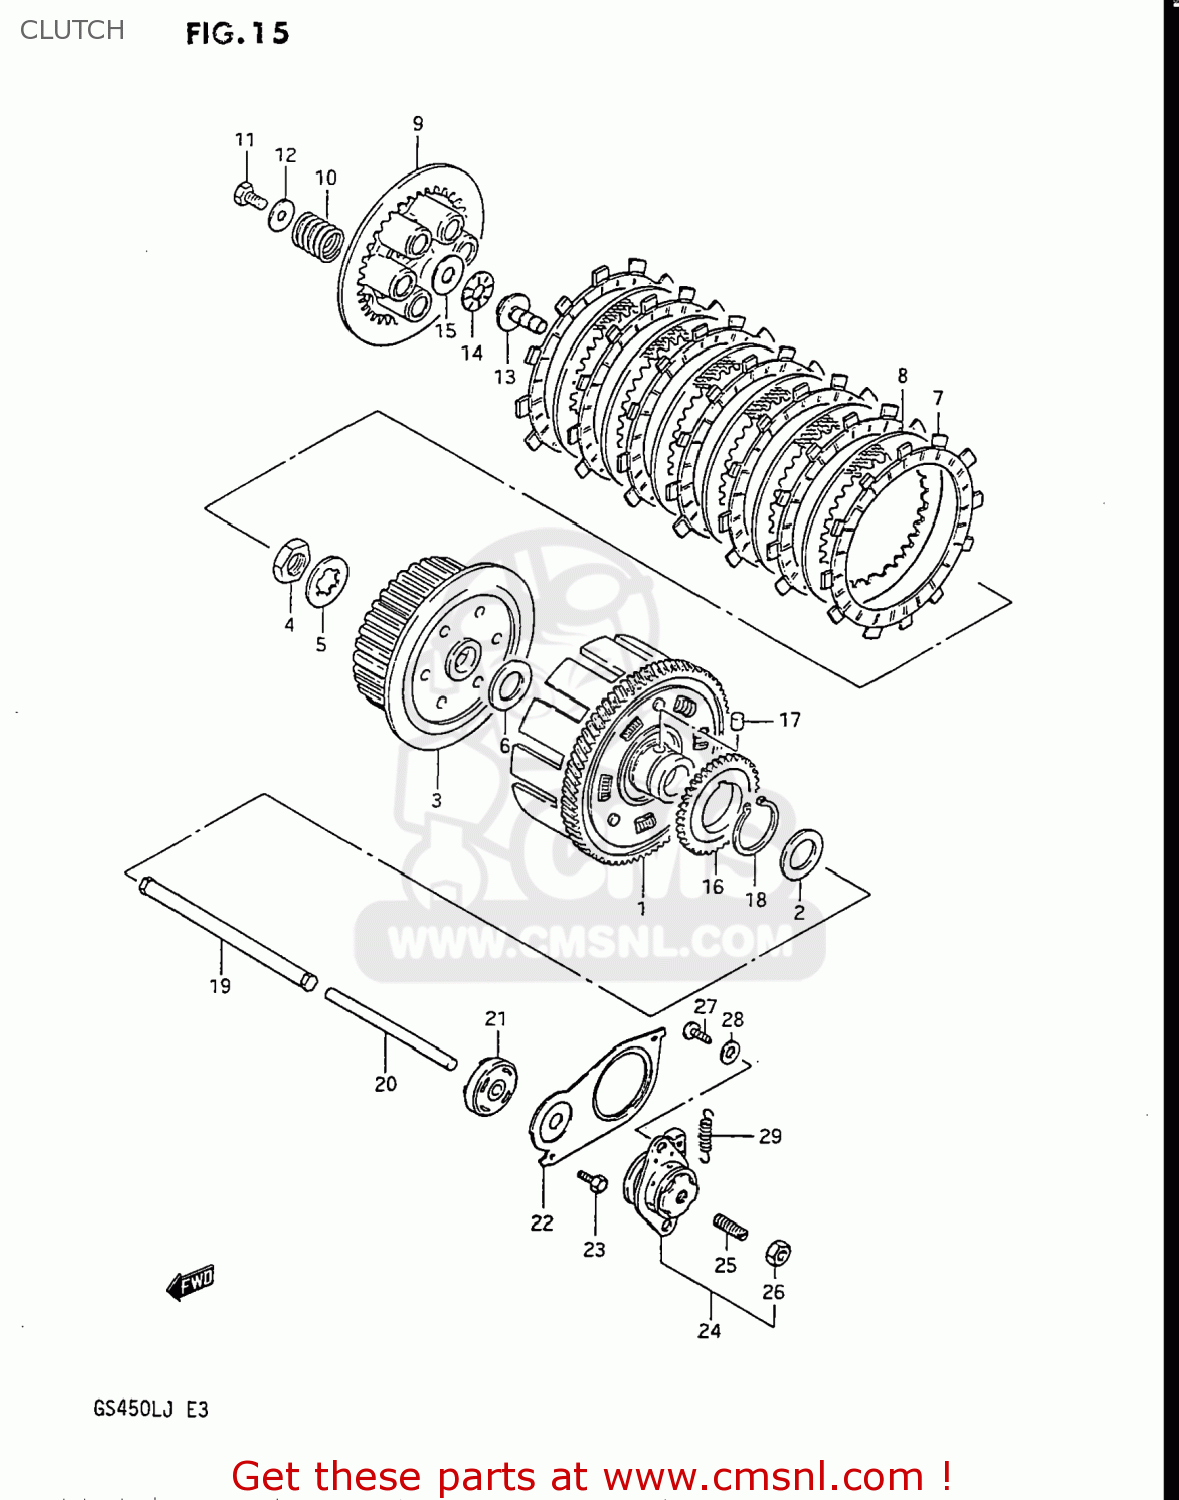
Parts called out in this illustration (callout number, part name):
1	GEAR ASSEMBLY,PRIMARY DRIVE
2	WASHER
3	HUB,CLUTCH SLEEVE
4	NUT (20MM)
5	WASHER,LOCK
6	WASHER(20X44X3)
7	PLATE,CLUTCH DRIVE (NAS)
8	PLATE,CLUTCH DRIVEN (NAS)
9	DISC,CLUTCH PRESSURE
10	SPRING
11	BOLT
12	WASHER
13	PIECE,CLUTCH PUSH
14	BEARING(15X28X2)
15	WASHER
16	GEAR,OIL PUMP DRIVE
17	PIN(6X6)
18	CIRCLIP
19	ROD,PUSH,R
20	ROD,CLUTCH PUSH
21	SEAL,OIL(6X34X10)
22	PLATE,CLUTCH PUSH ROD
23	BOLT
24	SCREW ASSY,CLUTCH RELEASE
25	SCREW(6X25)
26	NUT 6MM
27	SCREW
28	WASHER
29	SPRING
